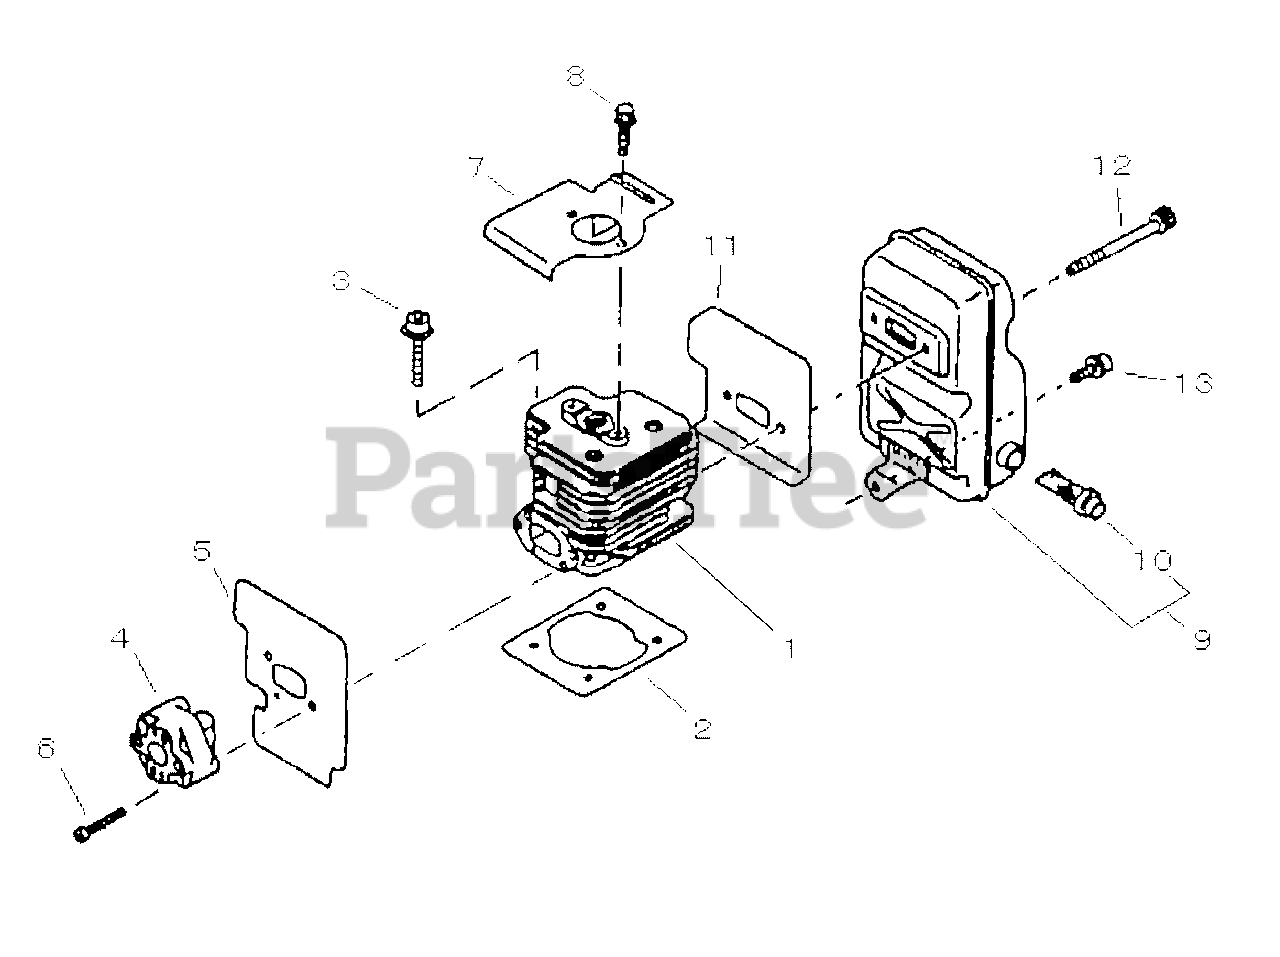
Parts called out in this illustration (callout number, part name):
1	CYLINDER
2	GASKET, CYLINDER
3	BOLT M5×22
4	INSULATOR
5	SHIELD, HEAT
6	SCREW M5×35
7	COVER, CYLINDER
8	BOLT M5×10
9	MUFFLER ASSY
10	SCREEN, SPARK ARRESTER
11	GASKET, MUFFLER
12	BOLT M6×70
13	BOLT, FLANGE M6×12
